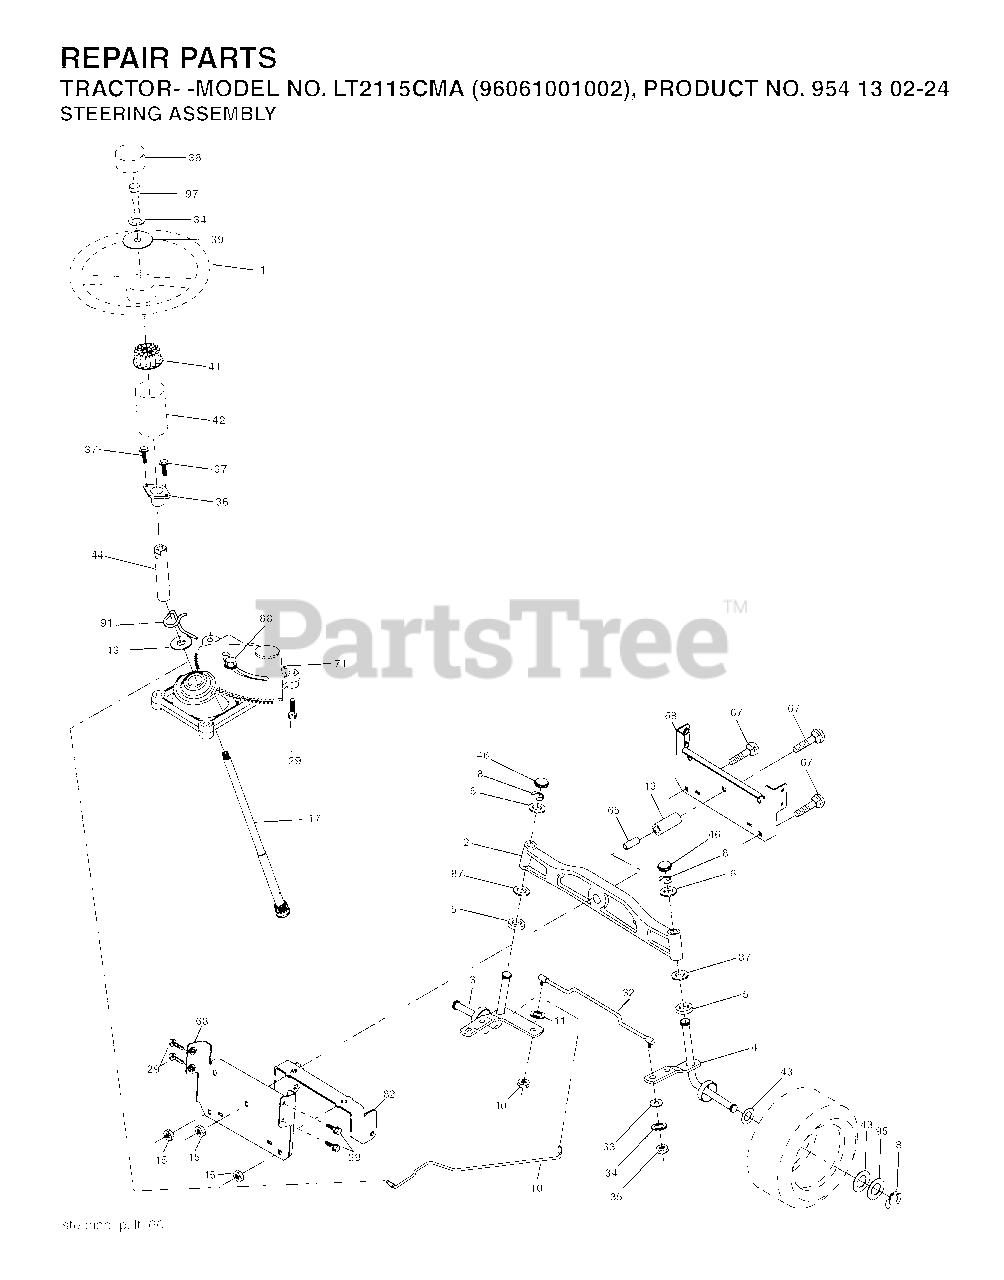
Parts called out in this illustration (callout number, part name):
1	WHEEL.STEERING.PREM.2.BLK
2	AXLE ASSY FRONT
3	SPINDLE.ASM.LH.15"TIRES
4	SPINDLE.ASM.RH.15"TIRES
8	RING CLIP
10	DRAGLINK.15".TIRES.2001
11	WASHER, LOCK 3/8
13	TUBE, PIVOT AXLE
15	NUT
17	SHAFT STEERING SPLINE
29	SCREW, 3/8-16X3/4
32	ROD.ASM.TIE.BALL.JOINT.NOVAN
33	WASHER M
34	LOCKWASHER
35	NUT, CROWNLOCK
36	BUSHING, STEERING
38	INSERT.CAP.STRG.WH.BLACK
39	WASHER.11/32
40	NUT CROWNLOCK 3/8-24
41	ADAPTER, WHEEL STNG..
42	BOOT.STEERING.SHAFT.BLACK
44	SHAFT.EXTEN.STRG.SPLINE
46	CAP.SPINDLE
65	SPACER BRACE AXLE
67	BOLT CARRIAGE
68	BRACE.AXLE.15"TIRES
71	STEERING ASM
82	BRACKET
87	WASHER, FLAT .781 X 1 1/2"
88	BOLT, SHOULDER 7/16-20
91	CLIP.STEERING
95	WASHER.HARDENED
